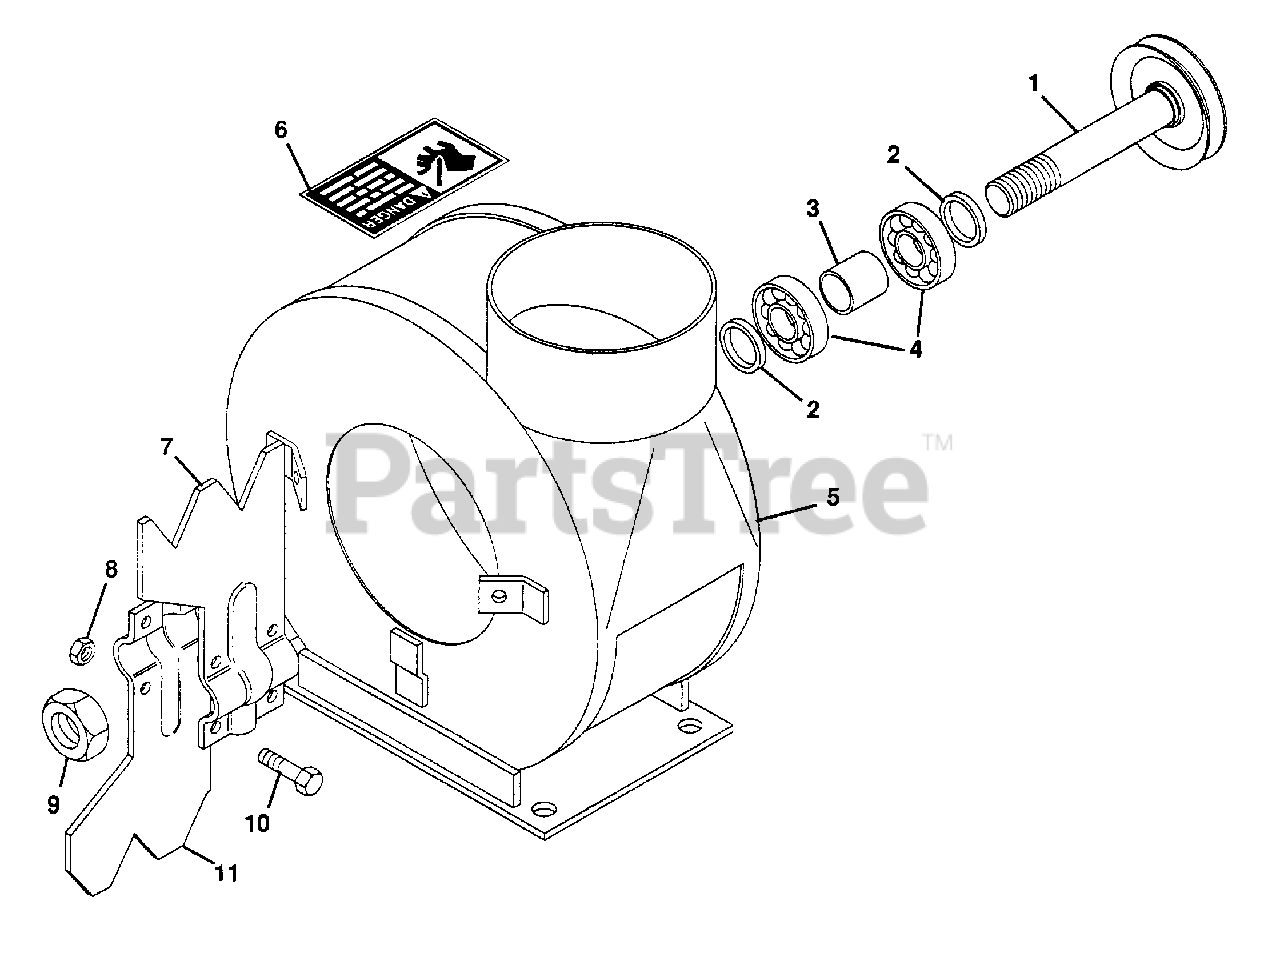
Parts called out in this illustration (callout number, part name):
1	Weldment, Spindle
2	Washer, 1.000/1.031x1.50x.125
3	Spacer
4	Bearing, Ball 1.000x2.000x.562
5	Weldment, Blower Housing
6	Decal, Danger Hand
7	Blade, Fan
8	Nut, Lock 5/16-18
9	Nut, Hex 1-14 Jam Lock
10	Bolt, Hex 5/16-18x.625
11	Blade, Fan
